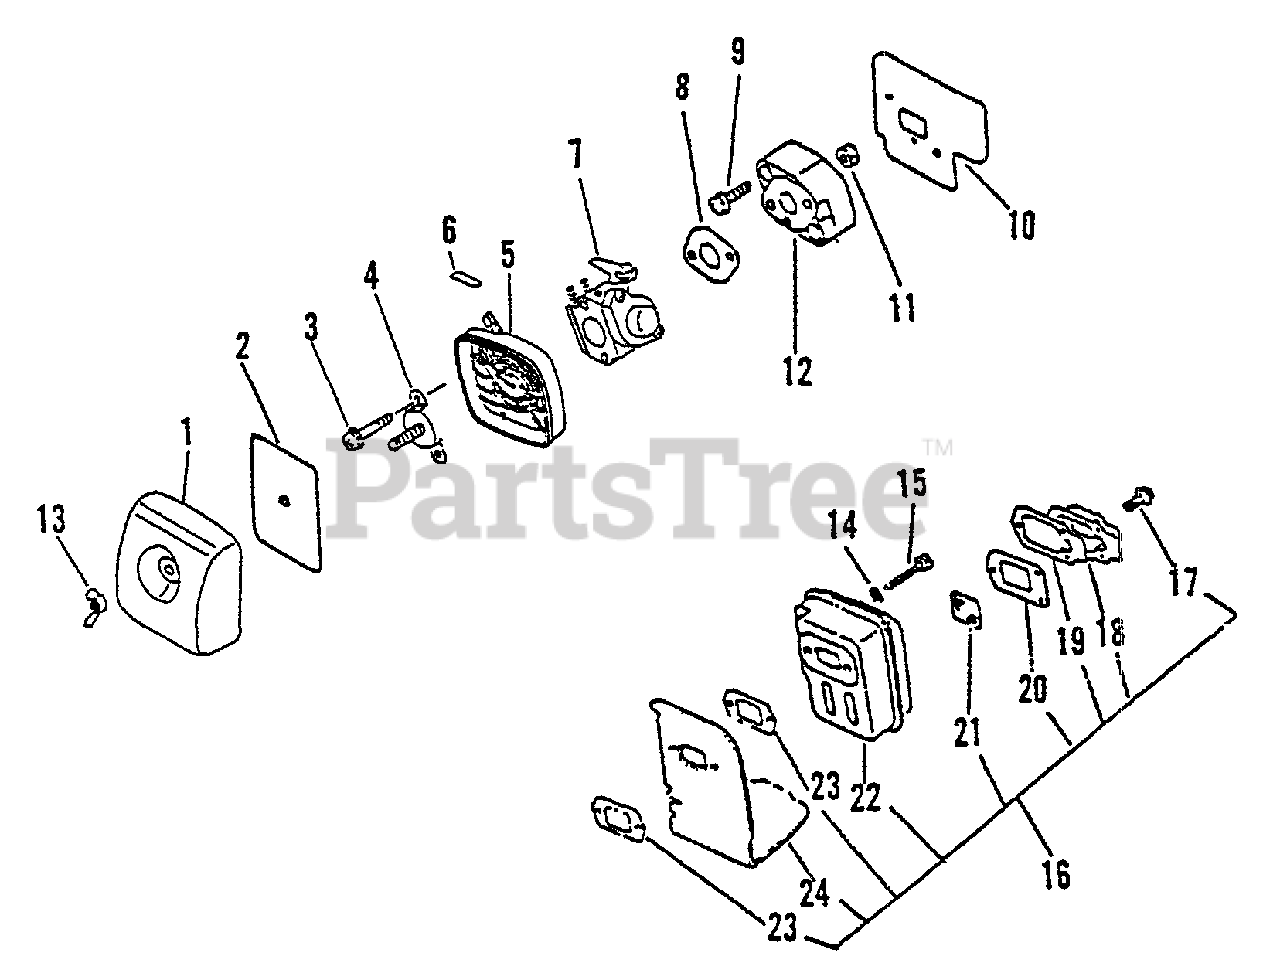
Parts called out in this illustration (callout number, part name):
1	COVER, AIR FILTER
2	FILTER, AIR - SINGLE LAYER
3	SCREW 5×65
4	PLATE, PREVENT
5	AIR FILTER CASE ASSY
6	LABEL, CHOKE
7	CARBURETOR - C1U-K26A
8	GASKET, INTAKE
9	SCREW 5×22
10	GASKET, INTAKE
11	NUT M5
12	INSULATOR, INTAKE
13	WINGNUT - 6
14	WASHER, FLAT 5.5×10×0.8
15	BOLT 5×55
16	MUFFLER ASSY
17	SCREW 4×10
18	GUIDE, EXHAUST - INNER
19	GUIDE, EXHAUST
20	GASKET, EXHAUST
21	SCREEN, SPARK ARRESTER
23	GASKET, EXHAUST
24	COVER, MUFFLER
